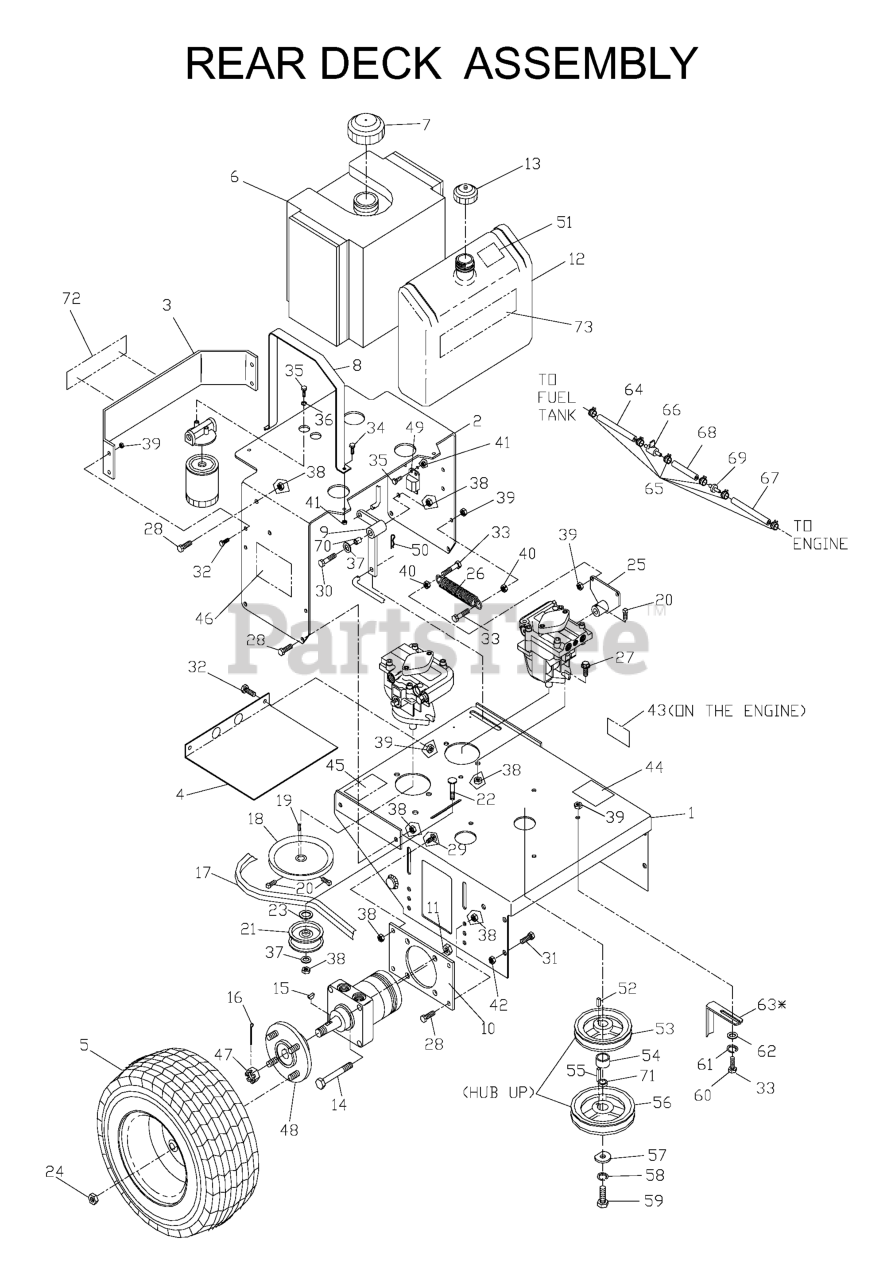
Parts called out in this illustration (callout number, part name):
1	REAR DECK W/DECALS
2	TANK SUPPORT, WLDMT
4	LOWER BELT SHIELD
5	WHEEL, COMPLETE
8	TANK STRAP
9	BELL CRANK
10	MOTOR MOUNT, 36
11	NUT 1/2-13 HEX NYLOC ZD
13	HYDRAULIC CAP
14	HCS 1/2C X 2 3/4
15	KEY, #808 WOODRUFF
16	COTTER PIN
17	TRANSMISSION BELT
19	KEY 5 MM SQ X 25 MM
20	SCREW 5/16C X 5/8 SQ HEAD
21	IDLER PULLEY
22	RHSNB 3/8C X 2
23	WASHER 1/2 FLAT
24	LUG NUT 1/2F
25	PUMP ARM WLDMT
26	SPRING-TRANS
27	4CS 3/8C X 1 SERRATED HEAD
28	HCS 3/8-16X1.GRD.5.ZD
29	RHSNB 3/8C X 1
30	HCS 3/8C X 2
31	HCS 7/16-14 X 1 GR 5 ZD
32	HCS 5/16C X 3/4
33	HCS 5/16C X 1 3/4
34	HCS 1/4 X 1
35	HCS 1/4C X 5/8
36	LOCKWASHER 1/4"
37	WASHER 3/8 FLAT
38	NUT 3/8C CENTERBLOCK
39	NUT 5/16C CENTERLOCK
40	NUT 5/16C WHIZ
41	NUT 1/4C CENTERLOCK
42	NUT 7/16C CENTERLOCK
43	DECAL, EXHAUST
44	DECAL, PROP. 65
45	DECAL, DANGER
46	DECAL, CROWN H
47	NUT 3/4-16 HEX SLTD GR5 ZD
48	HUB.WHEEL.ZTR
50	HAIRPIN #2
51	DECAL, HYDRAULIC FLUID
52	KEY 1/4 SQ X 3/4
55	KEY 1/4 SQ X 1 1/8
56	PULLEY, ENGINE
57	WASHER, CRANKSHAFT
58	WASHER 7/16 LOCK
59	HCS M10-1.5X35MM
60	HTB M8-1.125 X 25MM
61	WASHER.LOCK.HVY.HLCL.SPR.5/16
62	WASHER 5/16 FLAT
63	BELT GUIDE
64	FUEL LINE 16"
65	HOSE CLAMP
66	FUEL VALVE
67	GAS LINE 10"
68	GAS LINE 3 1/2"
69	FUEL FILTER
70	BUSHING, SLEEVE
71	BUSHING, 10GA MACHINERY
72	DECAL, HUSQVARNA LOGO 9.25"
73	DECAL, WH3614
539100141	HCS 7/16F X 1 1/2
539100567	HCS M8-1.25 X 30MM
539102220	MOTOR MOUNT, 48
539103462	BELT GUIDE - LONG
539103463	BELT GUIDE, SHORT
539104628	WHEEL
539104792	DECAL, WH4817
539104832	DECAL WH3615
539104993	FUEL LINE 14"
539912234	VALVE STEM TR-412
